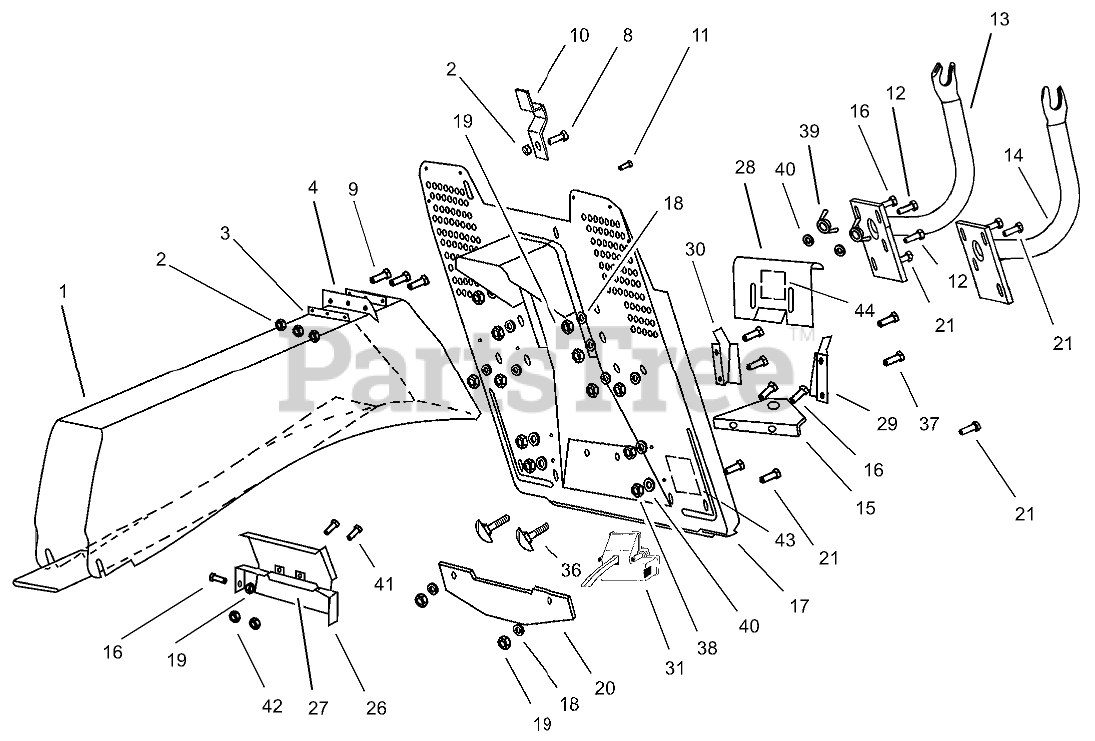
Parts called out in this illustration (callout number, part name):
1	TUNNEL
2	NUT-HEX
3	PLATE-SUPPORT
4	SEAL-RUBBER
9	SCREW-SFH
10	COVER-SWITCH
11	BOLT-CARRIAGE
13	SUPPORT-COLLECTOR, RIGHT
14	SUPPORT-COLLECTOR, LEFT
15	HITCH-TOW
16	SCREW-HEX
17	COLLECTOR PLATE ASM
18	WASHER-FLAT
19	NUT-LOCK, NI
20	SUPPORT-HITCH, TOW
21	SCREW-HEX
26	BRACKET-SHIELD, PROTECTIVE
27	SHIELD-PROTECTIVE
28	SHIELD-ADJUSTABLE
29	CHUTE-LEFT REAR PLATE
30	CHUTE-RIGHT REAR PLATE
31	OVERLOAD SWITCH ASM
32	LEVER-OVERLOAD SWITCH ACTUATION
33	HOUSING-OVERLOAD SWITCH UPPER
34	HOUSING-OVERLOAD SWITCH LOWER
35	PIN-OVERLOAD SWITCH
36	BOLT-CARR
37	SCREW-HH
38	NUT-LOCK
39	NUT-WING
40	WASHER-FLAT
41	BOLT-CARRIAGE
42	NUT-LOCK
43	DECAL-BYPASS, HYDRO
44	DECAL-POSITION, BAGGING
